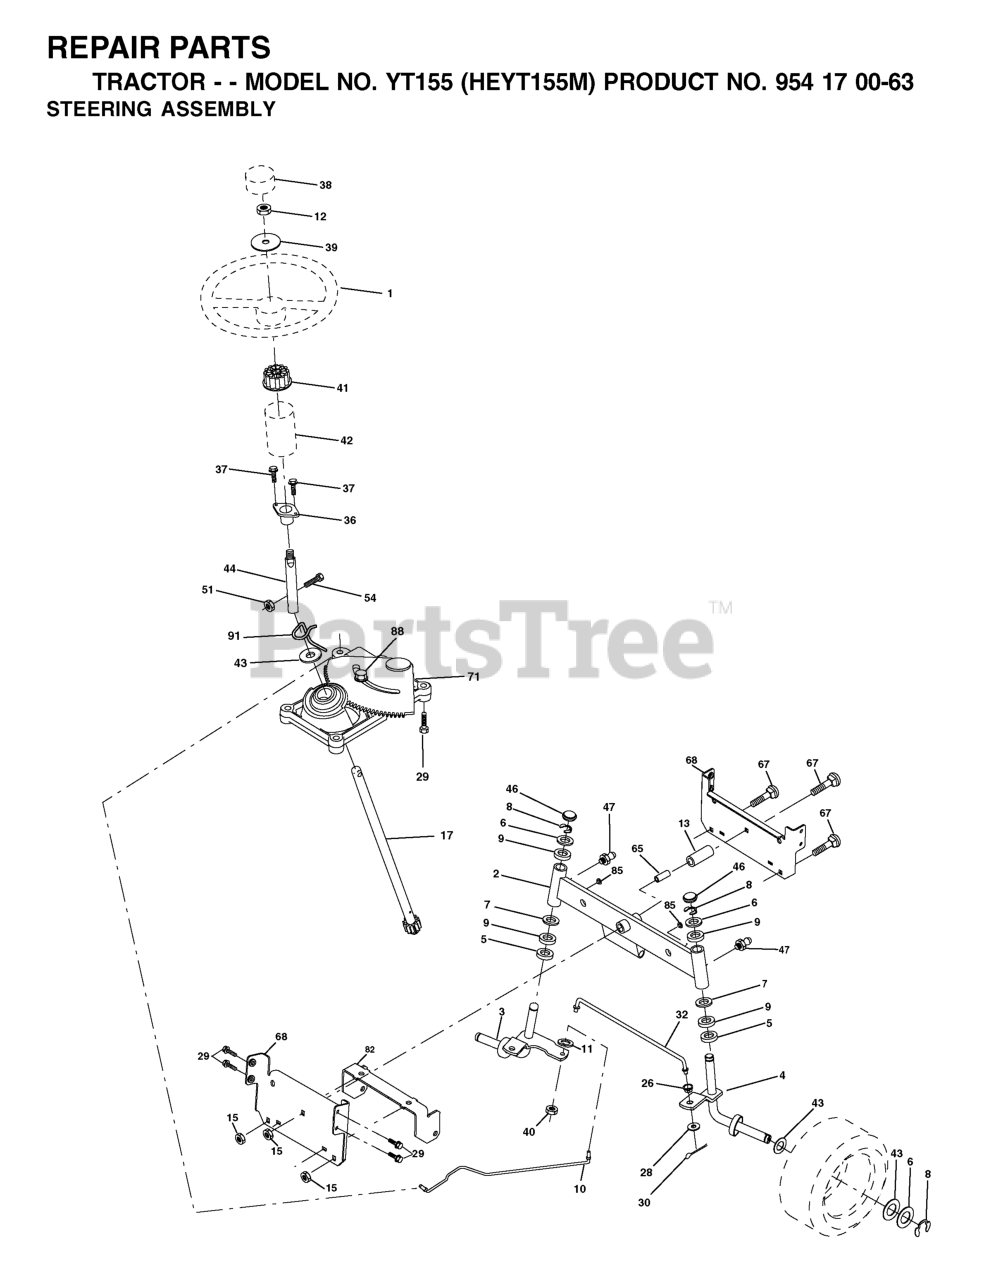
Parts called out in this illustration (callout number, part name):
1	STEERING WHEEL
2	AXLE ASM.
3	SPINDLE.ASM.LH.15"TIRES
4	SPINDLE.ASM.RH.15"TIRES
5	THRUST WASHER
9	BRNG T
10	DRAGLINK.15".TIRES.2001
11	WASHER, LOCK 3/8
12	NUT.HEX.1/2-20
13	TUBE, PIVOT AXLE
15	NUT
17	SHAFT ASM, STEERING
26	BUSHING.DRAGLINK (2 2)
28	WASHER
29	SCREW 3/8-16X3/4
30	COTTER PIN
32	TIE ROD
36	BUSHING, STEERING
37	SCREW.TT.#10-32X.5.3/8.FLANGE
38	CAP.WHEEL.STEERING.GREY
39	Washer 9/16 ID x 1 1/2 OD 11 Ga. Zin
40	GRIPCO NUT
41	STEERING WHEEL ADAPTOR
42	BOOT STEERING
44	EXT, STEERING SHAFT
46	CAP.SPINDLE.BLACK
47	ZERK M
51	NUT.CROWNLOCK.1/4-28
54	Bolt Hex 1/4-28 unf x 1-1/4 Gr. 8
65	SPACER BRACE AXLE
67	BOLT
68	BRACE.AXLE.15"TIRES
71	STEERING ASM
82	BRACKET
85	FASTENER.XMAS.TREE
88	BOLT, SHOULDER 7/16-20
91	CLIP.STEERING
